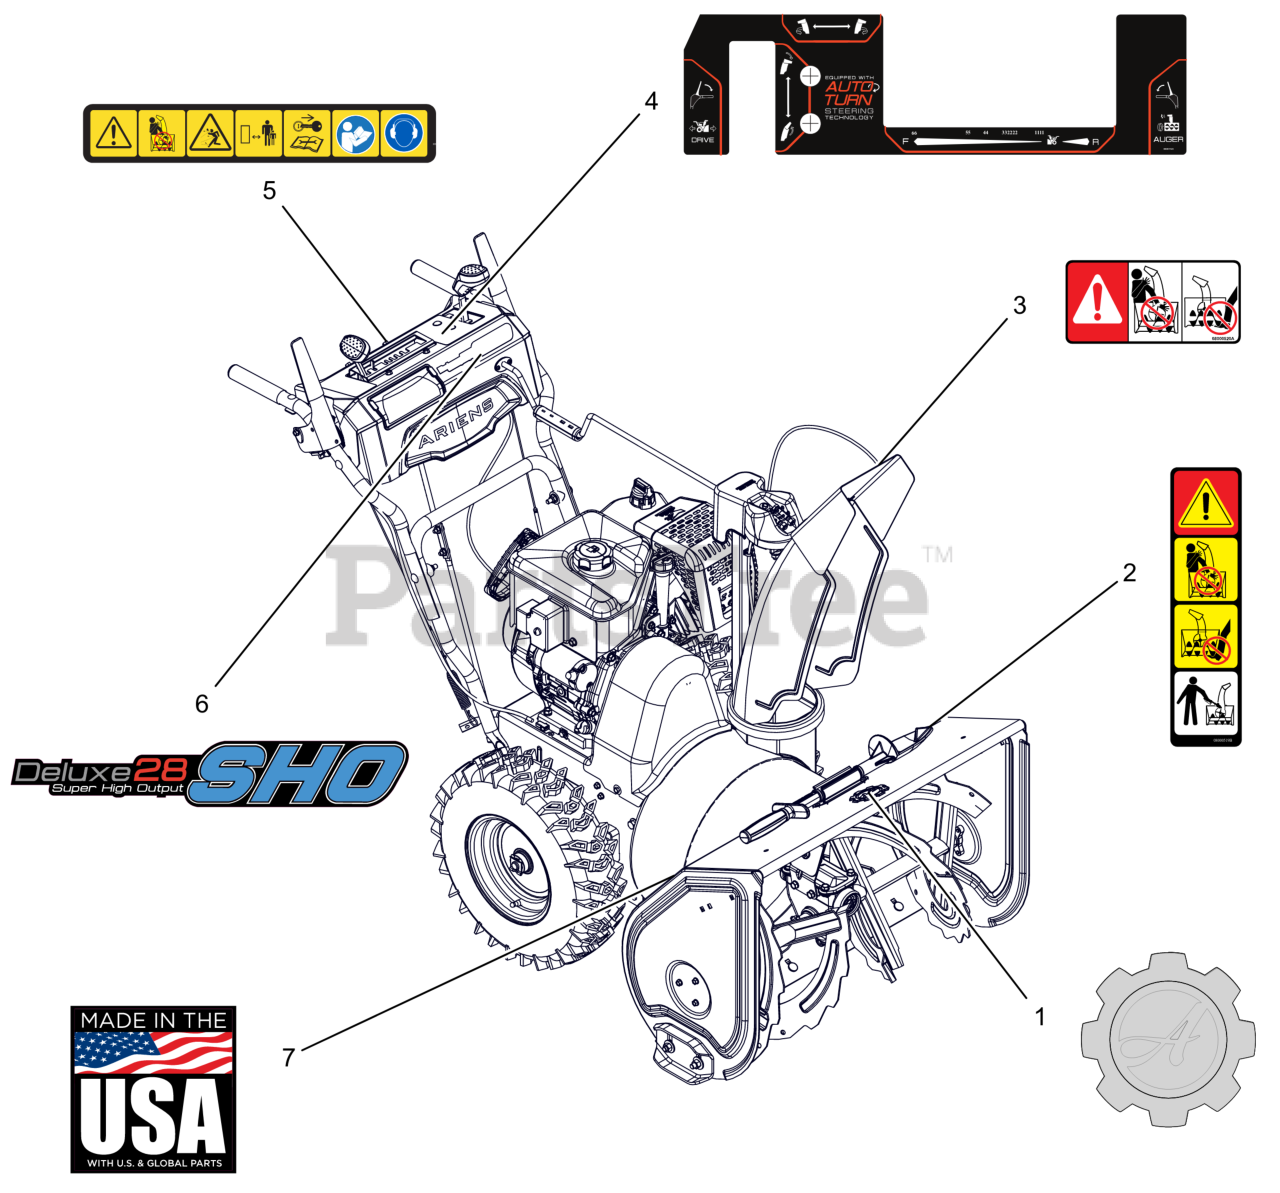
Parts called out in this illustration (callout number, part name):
1	DECAL, ARIENS-GEAR BADGE -THK
2	DECAL, DANGER - ROTATING PARTS
3	DECAL, DANGER
4	DECAL,CONTROL-SML,AT,ID
5	DECAL,DASH - SAFETY
6	DECAL,SMALL DASH-DLX 28 SHO
7	DECAL, MADE IN USA
